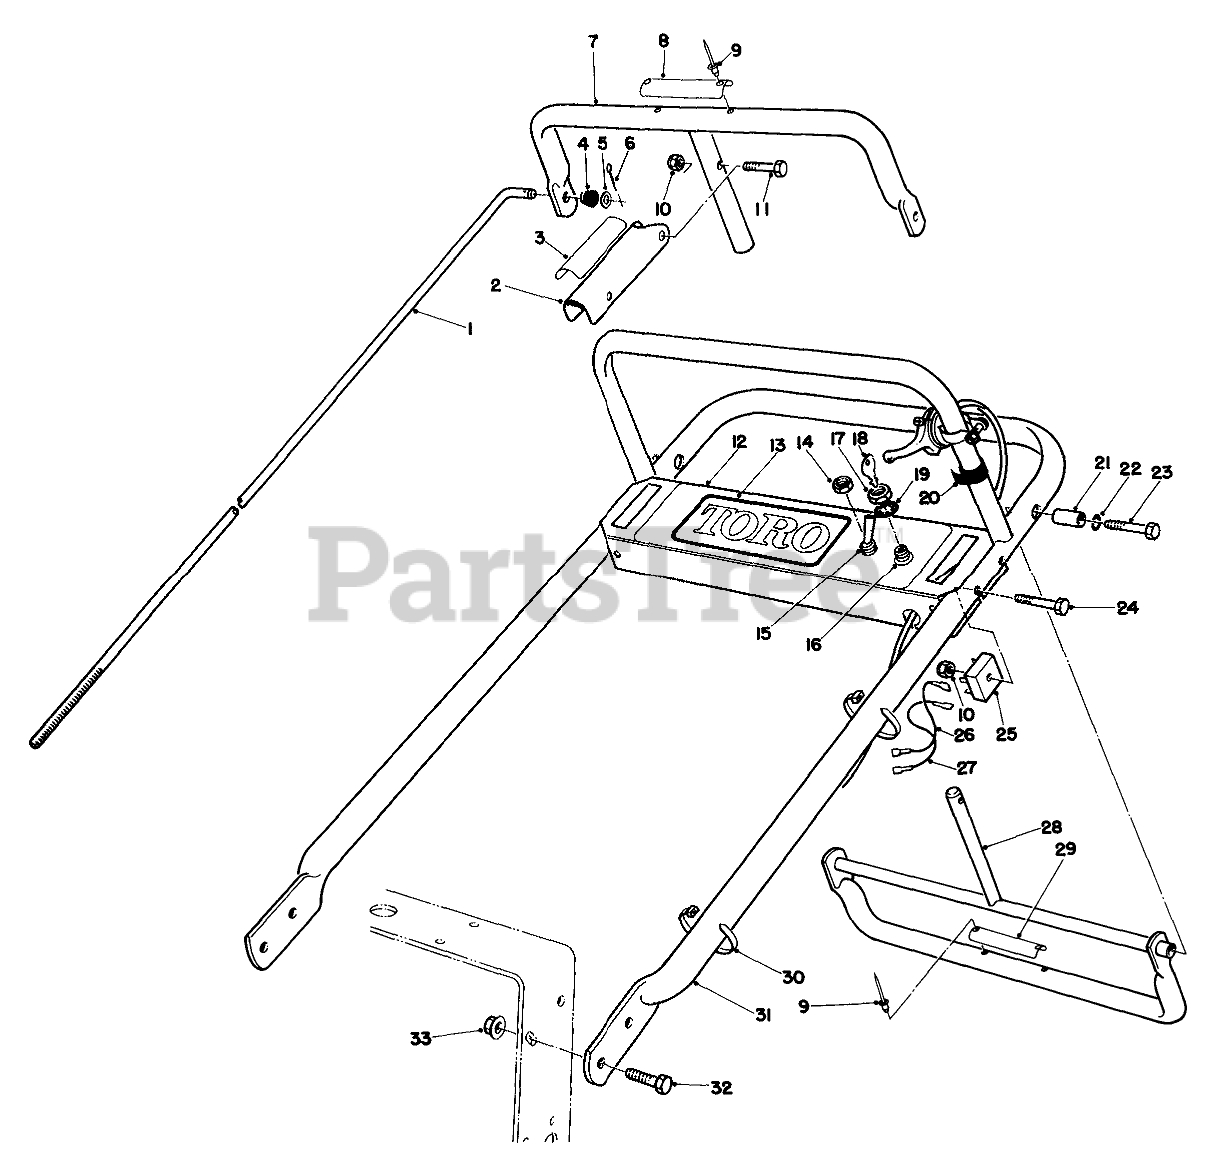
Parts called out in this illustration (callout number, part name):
1	ROD-CONTROL
2	Lever-Parking Brake
3	DECAL-LEVER, PARKING
4	GROMMET-RUBBER
5	WASHER-PLAIN
6	PIN-COTTER
7	Bar-Control
8	DECAL-CONTROL BAR
9	RIVET-BLIND
10	NUT-LOCK, NI
11	SCREW-SHH
12	Panel-Control
13	JLO PANEL DECAL
14	NUT
15	Switch
16	SWITCH-ON / OFF
17	NUT-HH
18	Key
19	WASHER-TOOTH, INTERNAL
20	THROTTLE CONTROL SHIM
21	PIVOT-SPACER
22	WASHER-LOCK
23	SCREW-HH
24	SCREW-SHH
25	RECTIFIER-BRIDGE
26	JLO WIRE HARNESS
27	WIRE ASM
28	Control-Pivot
29	DECAL-REVERSE HANDLE
30	TIE-CABLE
31	HANDLE-UPPER
32	SCREW-HHF
33	NUT-HF
